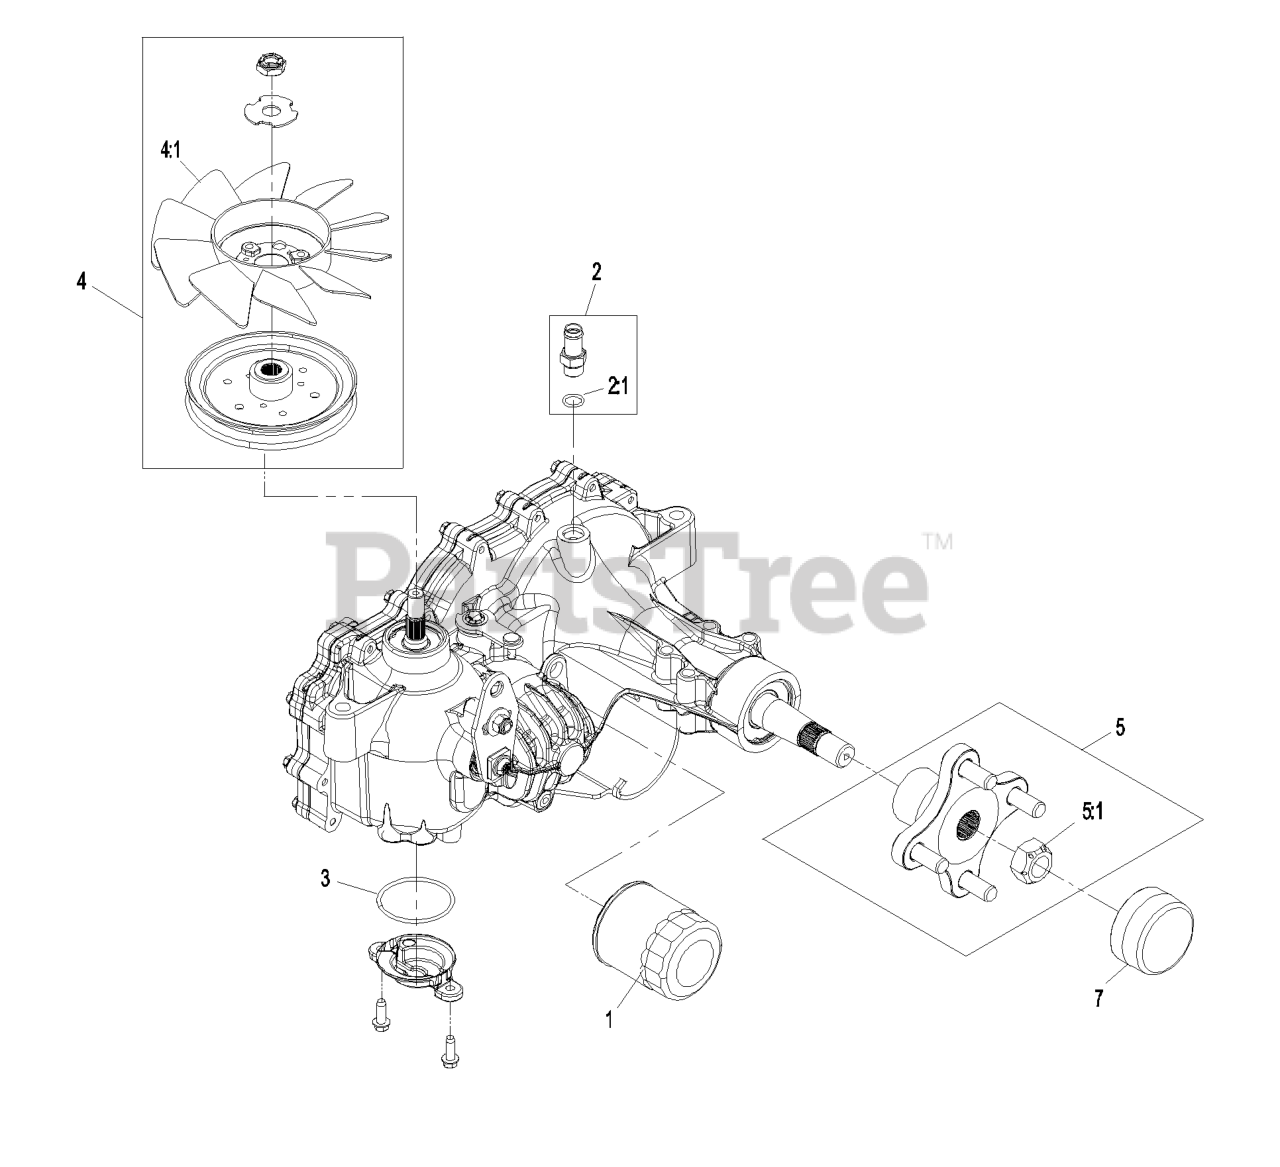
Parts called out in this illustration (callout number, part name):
1	ELEMENT-OIL FILTER, HYD
2	ADAPTER-STRAIGHT
3	O RING-SEAL
5	HUB KIT
5:1	NUT-HUB
7	COVER-NUT, AXLE
